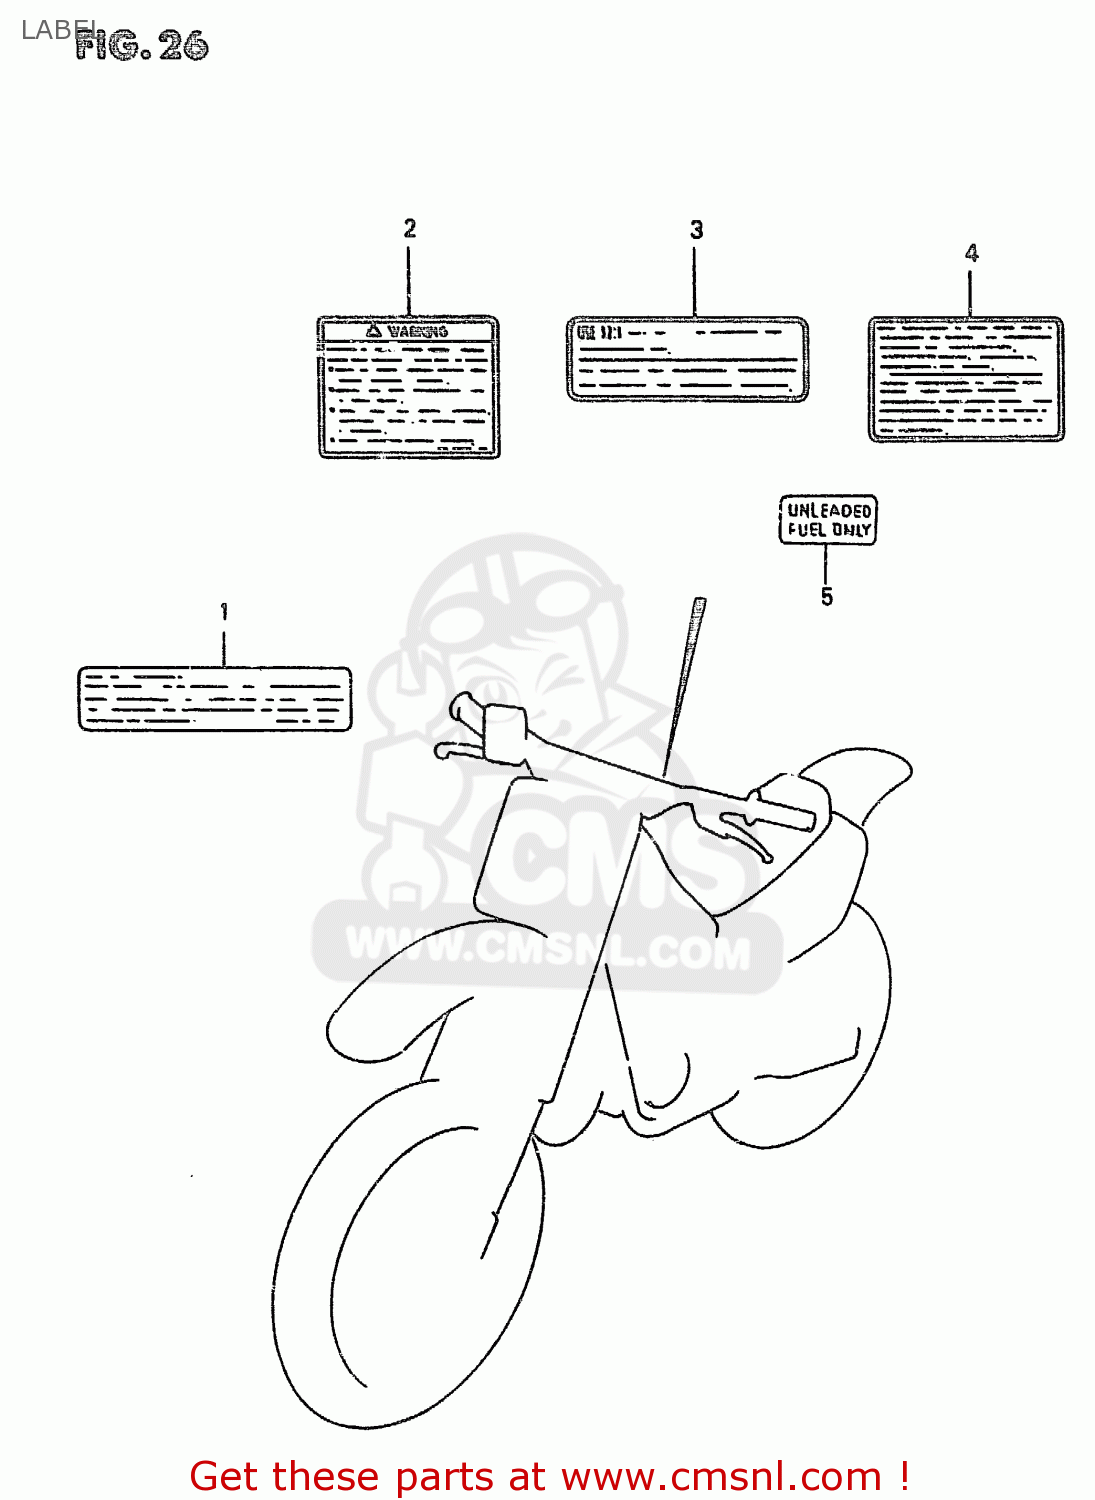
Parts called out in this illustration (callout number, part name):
1	PLATE,WARNING
2	LABEL,WARNING
3	LABEL,WARNING NO.2
4	LABEL,WARNING
5	LABEL,UNLEADED FUEL
6	MANUAL, OWNER'S
